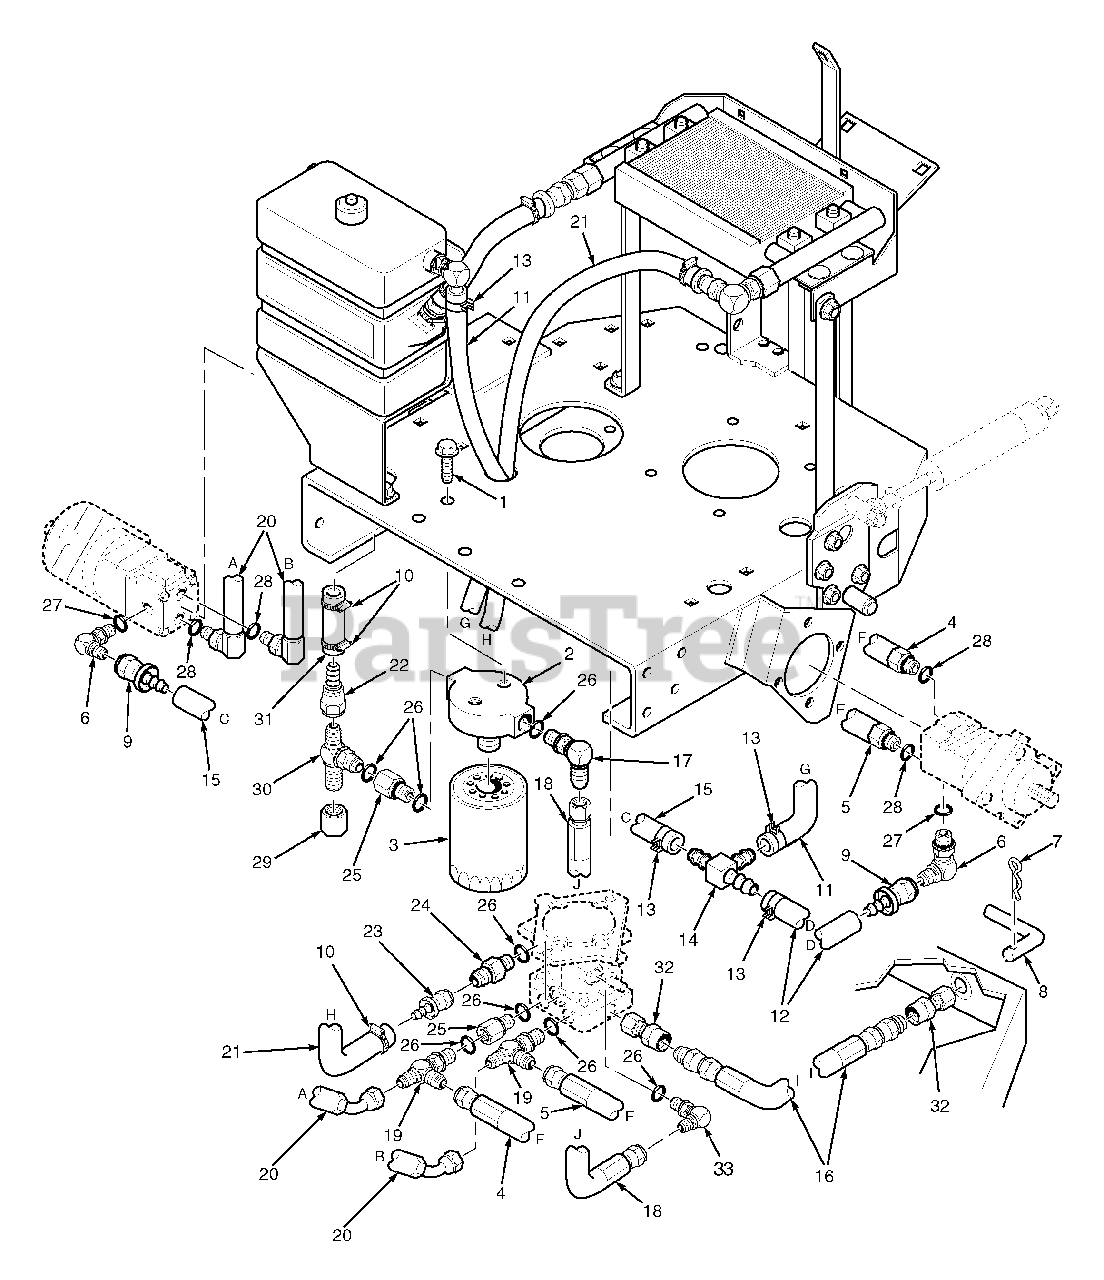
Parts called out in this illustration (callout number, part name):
1	Capscrew, 1/4-20 x1/2 Serr. Fl. Hex Head
2	Filter Head
3	Filter, Spin-On Lube
4	Hose Assembly
5	Hose Assembly
6	Elbow, 90 Degrees
7	Hairpin Cotter
8	Lever, Dump Valve
9	Connector, Flare Swivel with Hose Barb
10	Hose Clamp
11	Hose, 1/4 Pushlock,
12	Hose, 1/4 Pushlock,
13	Hose Clamp
14	Tee Union, Pushlock Hose
15	Hose, 1/4 Pushlock,
16	Hose, Dump Valve
17	Elbow, 90 Deg.
18	Inlet Hose, 3/4" ID
19	Tee, 1/2" Run
20	Motor Hose
21	Hose, Pump To Oil Cooler
22	Coupling, Flare Swivel
23	Coupling, Flare Swivel With Barb
24	Tube Union
25	O-Ring Bushing
26	O-Ring
27	O-Ring
28	O-Ring
30	Tee, JIC to O-Ring
31	Hose,
32	Compression Fitting
33	Elbow, 90 Deg.
